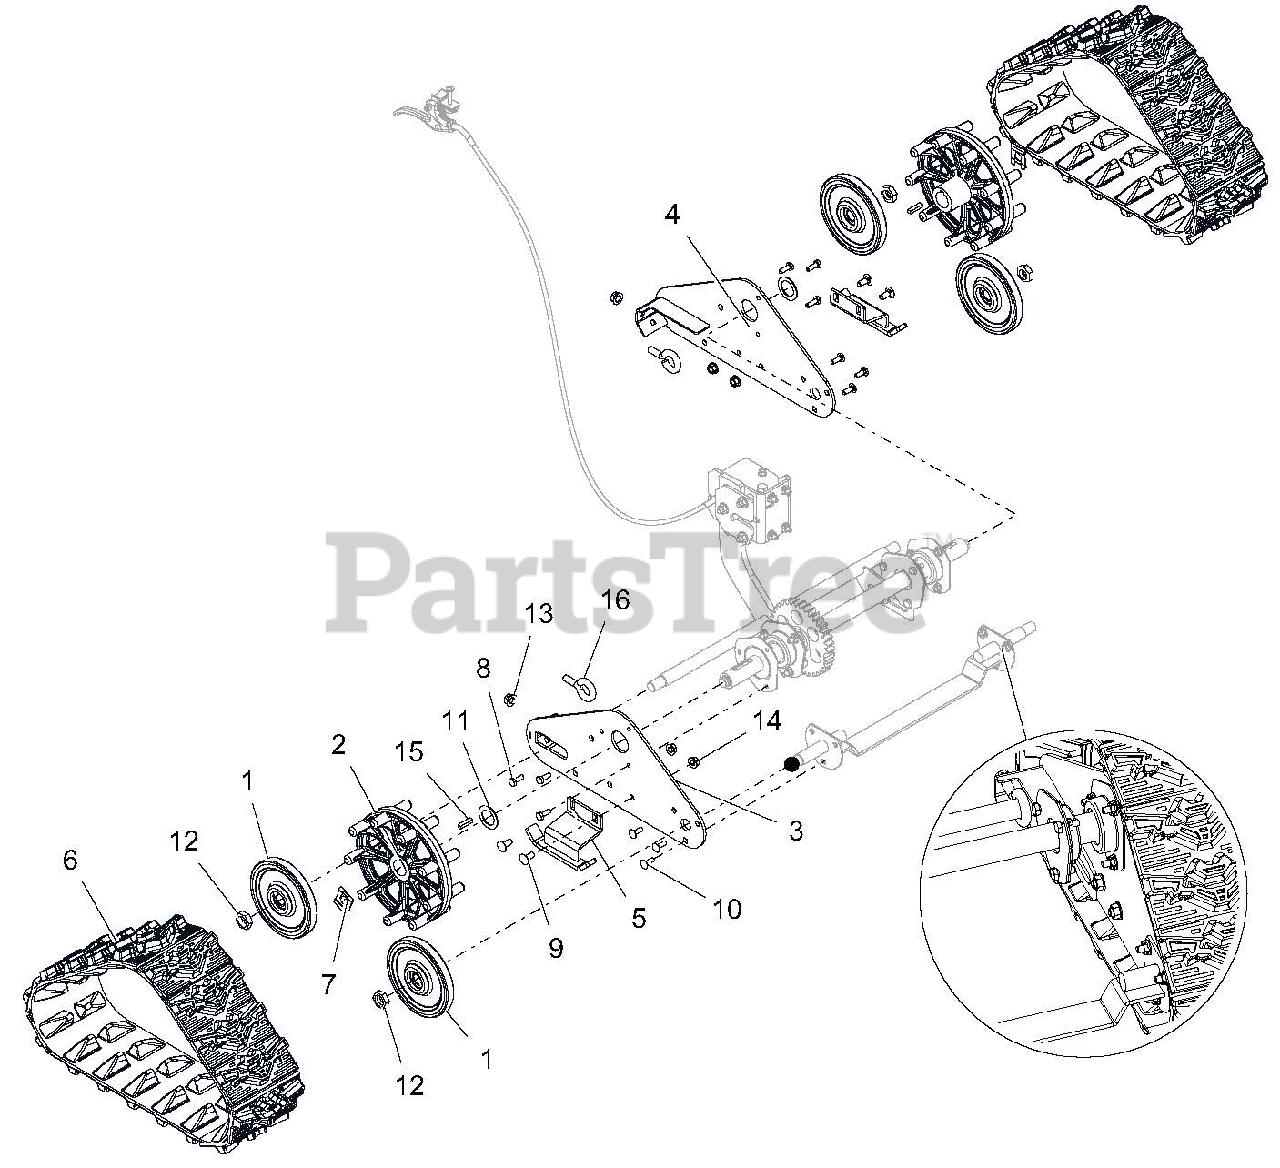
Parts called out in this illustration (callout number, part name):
1	WHEEL, BOGIE - SINGLE BEARING
2	WHEEL, MACHINED DRIVE
3	SIDE PLATE, RH COMPACT BLACK
4	SIDE PLATE, LH-COMPACT TRACK B
5	RUNNER, GUIDE-CMPT TRACK BLACK
6	TRACK, RUBBER COMPACT
7	CLIP, SNAP .625 DIA
8	@BLT-HEX .25-20X.75 GR5 YWZC
9	@BLT-RDHDSQNK .31-18X.75 G5YZ
10	@BLT-RDHDSQNK .25-20X.75 G5YZ
11	WSHR-FL-STL 1.010X1.505X.062YZ
12	@NUT-LK-NYL .625-18 YWZC
13	NUT-LK-CTR-FLG .38-16 YWZC
14	@NUT-LK-TOP-FLG .31-18 YWZC
15	KEY-RECT .25X.188X1.00
16	BLT-EYE .375-16X.880 YWZC
